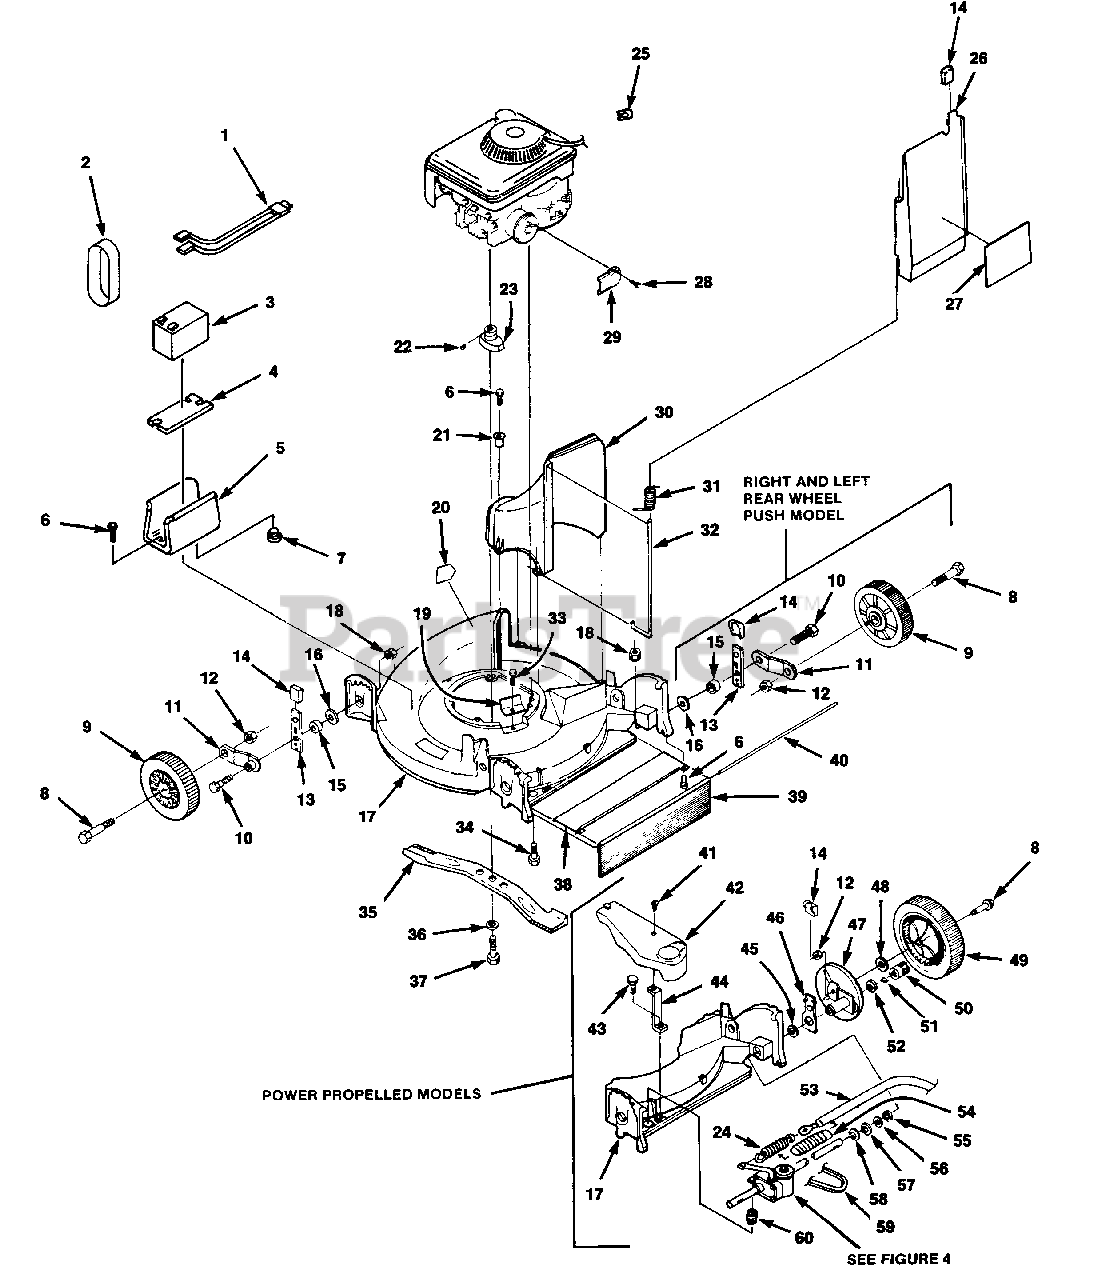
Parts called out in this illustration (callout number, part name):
1	LEAD- Battery
2	BAND- Rubber
3	BATTERY- 12 volt
4	PAD- Battery
5	HOLDER- Battery
6	SCREW- Hex hd. (1/4-20 x 3/4")
7	BUMPER
8	BOLT- Axle (3/8-16)
9	WHEEL & TIRE
10	BOLT- Hex hd. (5/16-18)
11	ARM- Wheel hgt. adj.
12	NUT- Hex (3/8-16)
13	SPRING- Index
14	KNOB- Index spring
15	SPACER- Index spring
16	WASHER- Flat (5/16")
17	DECK- 21"
18	NUT- Flange (5/16-18)
19	COVER- Belt opening
20	DECAL- Warning
21	EYELET- Stimpson
22	KEY- (5/8 x 5/32")
23	ADAPTER- Blade
24	SPRING- Traction lever
25	STOP- Rope
26	DOOR- Chute
27	DECAL- Door
29	DEFLECTOR- Muffler
30	CHUTE- Discharge
31	SPRING- Door chute
32	PIN- Hinge
33	SCREW- Hex hd. (1/4-20 x 1/2")
34	SCREW- (3/8-16 x 1 1/2")
35	BLADE- 21"
36	WASHER- Lock hvy. (7/16")
37	BOLT- Shoulder
38	COVER- Rear
39	FLAP- Drag
40	ROD- Drag flap
42	COVER- Drive
44	SUPPORT- Belt cover
45	SPACER- Hgt. adj.
46	SPRING- Index
47	DRIVE WHEEL SUPPORT
48	WASHER- Flat
49	WHEEL & TIRE (drive)
50	PINION- R.H.
51	PAWL- Pinion
52	WASHER- Flat
53	CABLE- Traction
54	COVER- Spring
55	WASHER- Flat
56	WASHER- Shim
57	WASHER
58	RING- Eaton
59	BELT- Drive
60	SPRING- Compression
